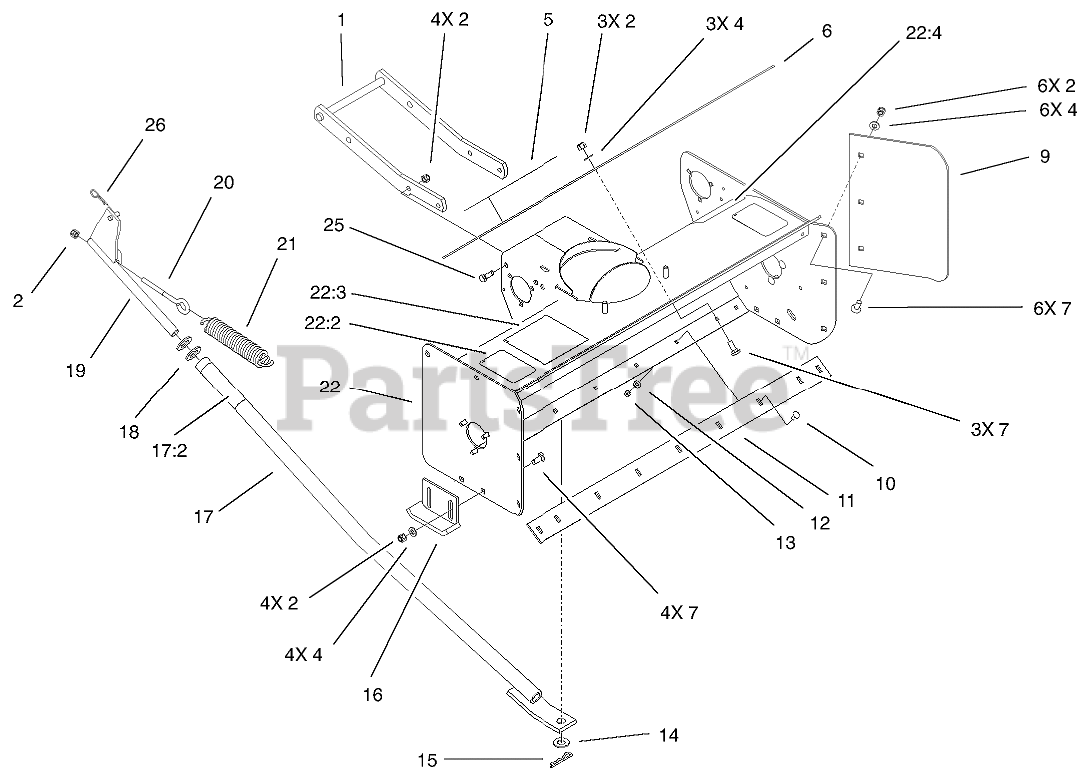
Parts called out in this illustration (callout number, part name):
1	FRAME-MOUNTING
2	NUT-LOCK, NI
4	WASHER-FLAT
5	DECAL-ATTACHMENT
6	PLATE-EXTENSION
7	BOLT-CARR
9	PLATE-EXTENSION, RH
10	SCREW-CARR
11	SCRAPER-REVERSIBLE
12	WASHER-FLAT
13	NUT-LOCK, NI
14	WASHER-FLAT
15	PIN-COTTER, HAIR
17	LIFT TUBE W/DECAL ASM
17:2	DECAL - WARNING
18	WASHER-FLAT
19	ROD-LIFT
20	EYEBOLT
21	SPRING
22	AUGER W/DECALS ASM
22:2	DECAL-DANGER
22:3	DECAL-WARNING
22:4	DECAL - WARNING
25	SCREW-HH
26	PIN-HAIR
